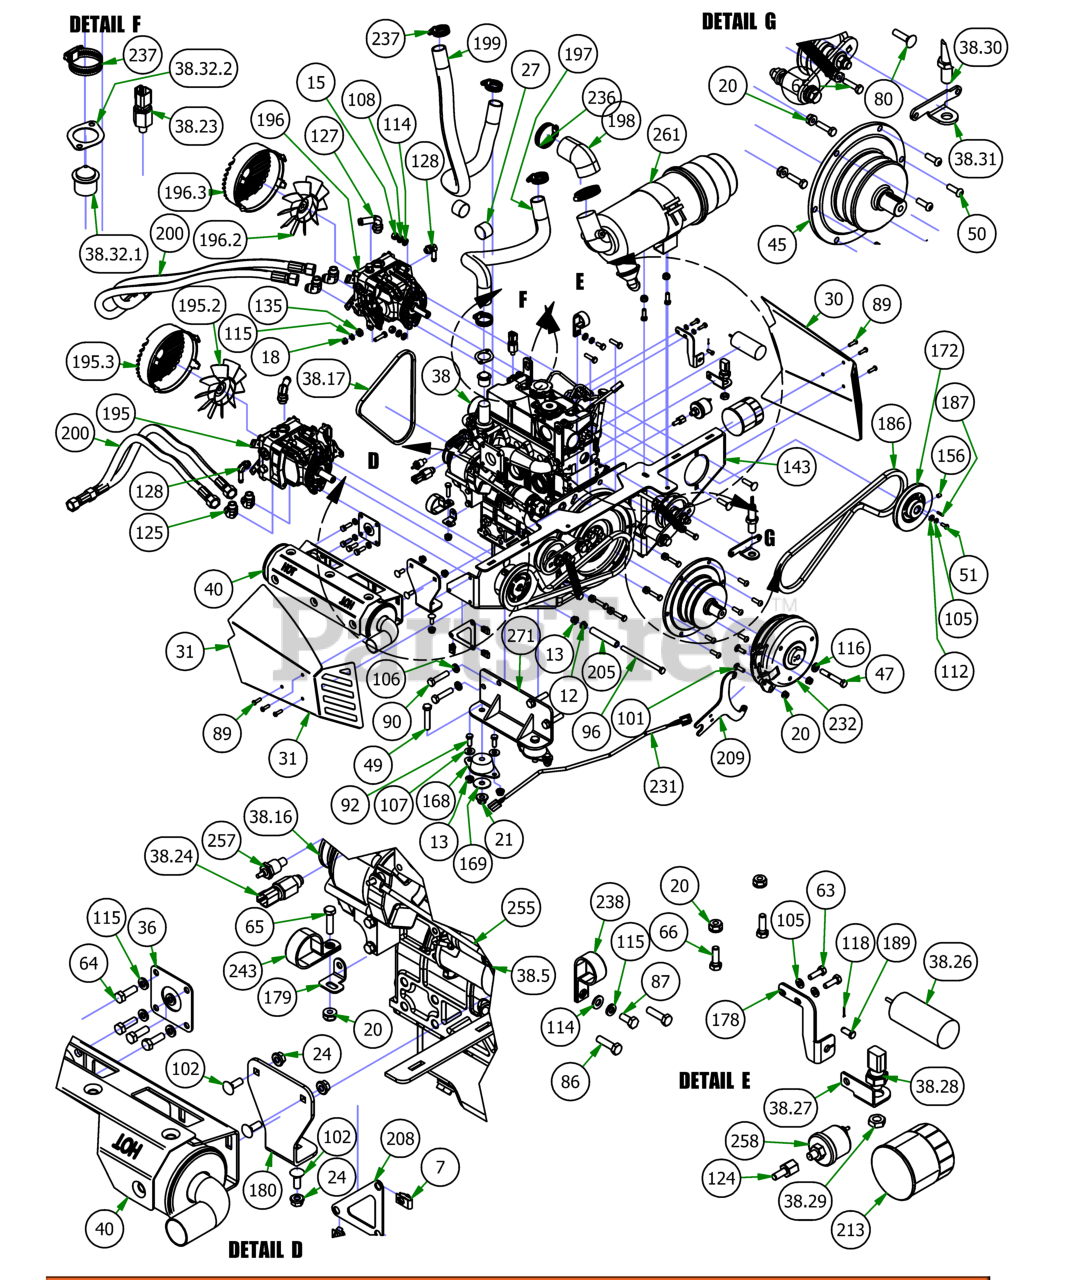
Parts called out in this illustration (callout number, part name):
7	1/4-20 Cage Nut
12	3/8-16 HEX SERRATED FLANGE NUT HARD/ZINC
13	3/8-16 NYLON INSERT FLANGE LOCKNUT (GR.F) ZINC
15	3/8" Hex Nut
20	5/16-18 Nylon Flange Nut
21	1/2-13 NYLON INSERT FLANGE LOCKNUT ZINC
24	5/16" Flange Nut
27	2019 Plastic Mesh Hose Loom
30	2019 Horizontal Pump Cover - Right
31	2019 Horizontal Pump Cover - Left
36	Diesel Muffler Gasket
38	24.7 hp Perkins Engine
38.17	Diesel Engine Belt
38.23	Oil Pressure Sensor
38.24	Coolant Temperature Sensor
38.26	Fuel Shutdown Solenoid
38.27	Barometric Pressure Sensor Bracket
38.28	Barometric Pressure Sensor
38.29	Pressure Sensor Nut for 1100cc Diesel
38.30	Crank Sensor w/ nut
38.31	Crank Sensor Bracket
38.32.1	1100cc Diesel Thermostat
38.32.2	1100cc Diesel Thermostat Gasket
40	2019 Renegade 1100cc Diesel Muffler
45	2019 Diesel Stub Shaft Double V
47	7/16"-20 x 3" Hex Bolt Gr. 8
48	1/2-13 X 90MM HEX FLANGE BOLT W/SHOULDER (GR.8) ZINC
49	1/2" x 3" Hex Bolt
50	5/16-18 x 1 Button Head Torx
51	M6-1.0 X 16MM Hex Bolt
60	3/8-16 X 3-1/2 HEX CAP SCREW (GR.5) ZINC
63	M6x1.0x 20mm 8.8 Hex Bolt
64	M8 x 1.25 x 25mm Hex Head Bolt
65	5/16 x 1 1/4 Hex Bolt
66	5/16" x 1" Bolt
80	3/8 x 1 1/2 Carriage Bolt
86	M8 x 1.25 x 30mm Hex Head Bolt
87	M8x1.20x20MM Hex head bolt
89	Hexagon Socket Button Head Cap Screw
90	12mm Bolt- Diesel
92	3/8" x 1" Hex Bolt
96	3/8-16 x 5 1/2 Hex Bolt
101	5/16" x 1" Carriage Bolt
102	5/16" x 7/8" Carriage Bolt
105	1/4" Lock Washer
106	1/2" Lock Washer
107	3/8" Flat Washer
108	3/8" Lock Washer
110	.635 ID X 1.120 OD X .140 THICK FLAT WASHER NYLON
112	1/4" Flat Washer
114	5/16" Flat Washer
115	5/16" Lock Washer
116	7/16" Lock Washer
118	3/32 X 1/2 Cotter-pin
124	8mm x 1/8 mpt Adaptor
125	2019 Outlaw 90 Degree Pump Fitting #6801-10-08
127	90 Degree Fitting, 1/2 x 3/4, 4601-8-8
128	90 Degree Fitting, 3/8 s 9/16
135	ACS Spacer 3/4x3/8x1/4
143	2020 Diesel Pump Plate Weldment - Painted
156	5/16-24 X 3/8 Set Screw
168	Rubber Compression Mount
169	Snubbing Washer
172	5" Pump Pulley
175	ZT and ACS Handle Spring
176	2019 Renegade Push Rod Assembly
176.1	2019 Renegade Push Rod
176.2	2019 Renegade Push Rod Adjuster
176.3	3/8" Fine Threaded Jam Nut
176.4	Spherical Rod End - Outlaw
176.5	Spherical Rod End - Outlaw
176.6	5/16" LH Fine Threaded Jam Nut
176.7	5/16" RH Fine Threaded Jam Nut
178	Diesel Throttle Bracket 4 Tier
179	Diesel Radiator Hose Clamp Bracket
180	2019 Diesel Muffler Bracket
183	2019 Renegade Belt Tensioner LH
184	2019 Renegade Belt Tensioner LH
186	2019 Renegade Pump Belt
187	5mm x 1.25" Key
189	1/4-5/8 Clevis Pin
195	2019 Rogue/Renegade Left Pump 16cc
195.2	Hydro Fan - Light/Pup/Outlaw XP
195.3	Fan Guard 6" - Fits Wheel
196	2019 Outlaw Renegade Right Pump 16cc
196.2	Hydro Fan - Light/Pup/Outlaw XP
196.3	Fan Guard 6" - Fits Wheel
197	2019 Diesel Radiator Hose Upper
198	2019 Diesel Air intake Hose
199	2019 Diesel Radiator Hose Lower
200	2019 Renegade Hydro Hose
205	3/8 hose 4" long
208	Pump Plate Clip Nut Holder
209	2019 Outlaw Renegade Clutch Bracket
213	CAT Oil Filter
231	Clutch Pigtail
232	Clutch for Diesel/Vanguard
236	2-1/2" Hose Clamp
237	1 1/8" Hose Clamp
238	Diesel Hydraulic Hose Clamp
243	Diesel Clamp 1 3/4" Vinyl
255	Red Battery Cable Alternator to Starter Cable
257	Coolant Temperature Sender
258	Oil Pressure Guage with Sender
261	Enginaire Canister VLR-Complet
271	2019 Diesel Motor Mount - Weldment
